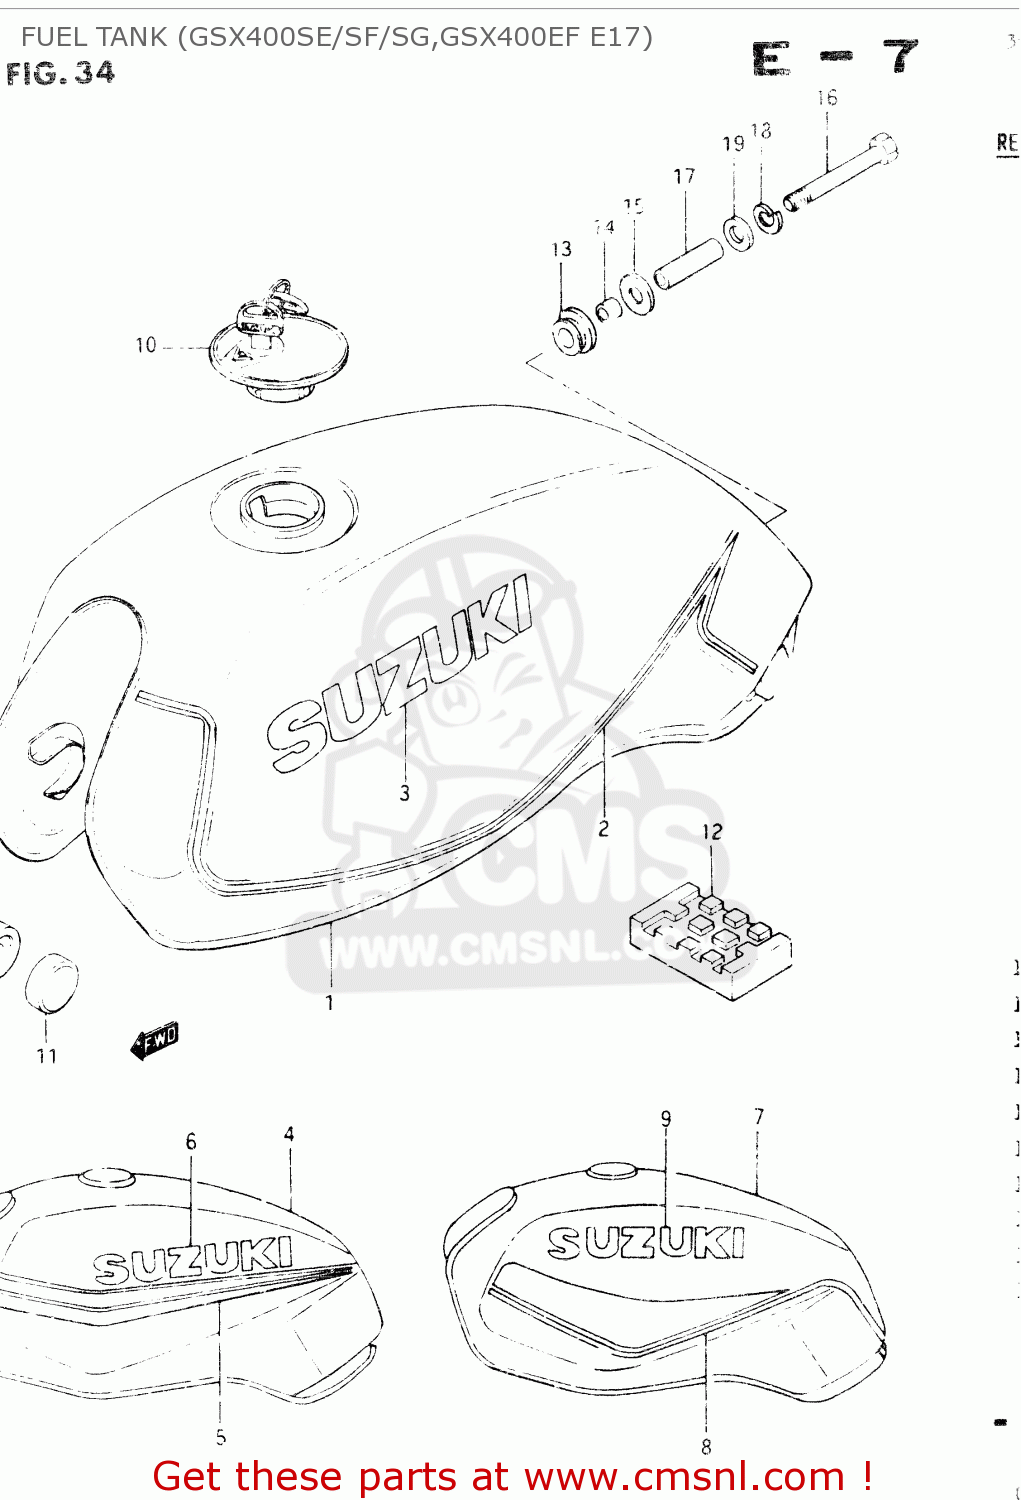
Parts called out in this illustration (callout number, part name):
1	TANK ASSY, FUEL
2	TAPE SET, FUEL TANK
3	EMBLEM,FUEL TANK
4	TANK ASSY, FUEL
5	TAPE SET, FUEL TANK
6	EMBLEM (WHITE)
7	TANK ASSY, FUEL
8	TAPE SET, FUEL TANK
9	EMBLEM
10	CAP SET,FUEL TANK
11	CUSHION
12	CUSHION,FUEL TANK CTR
13	CUSHION
14	SPACER (6.8X10X10)
15	WASHER (6.5X29X1.6)
16	BOLT 6X60
17	SPACER(6.5X10.5X40)
18	WASHER,LOCK
19	WASHER, LOWER
